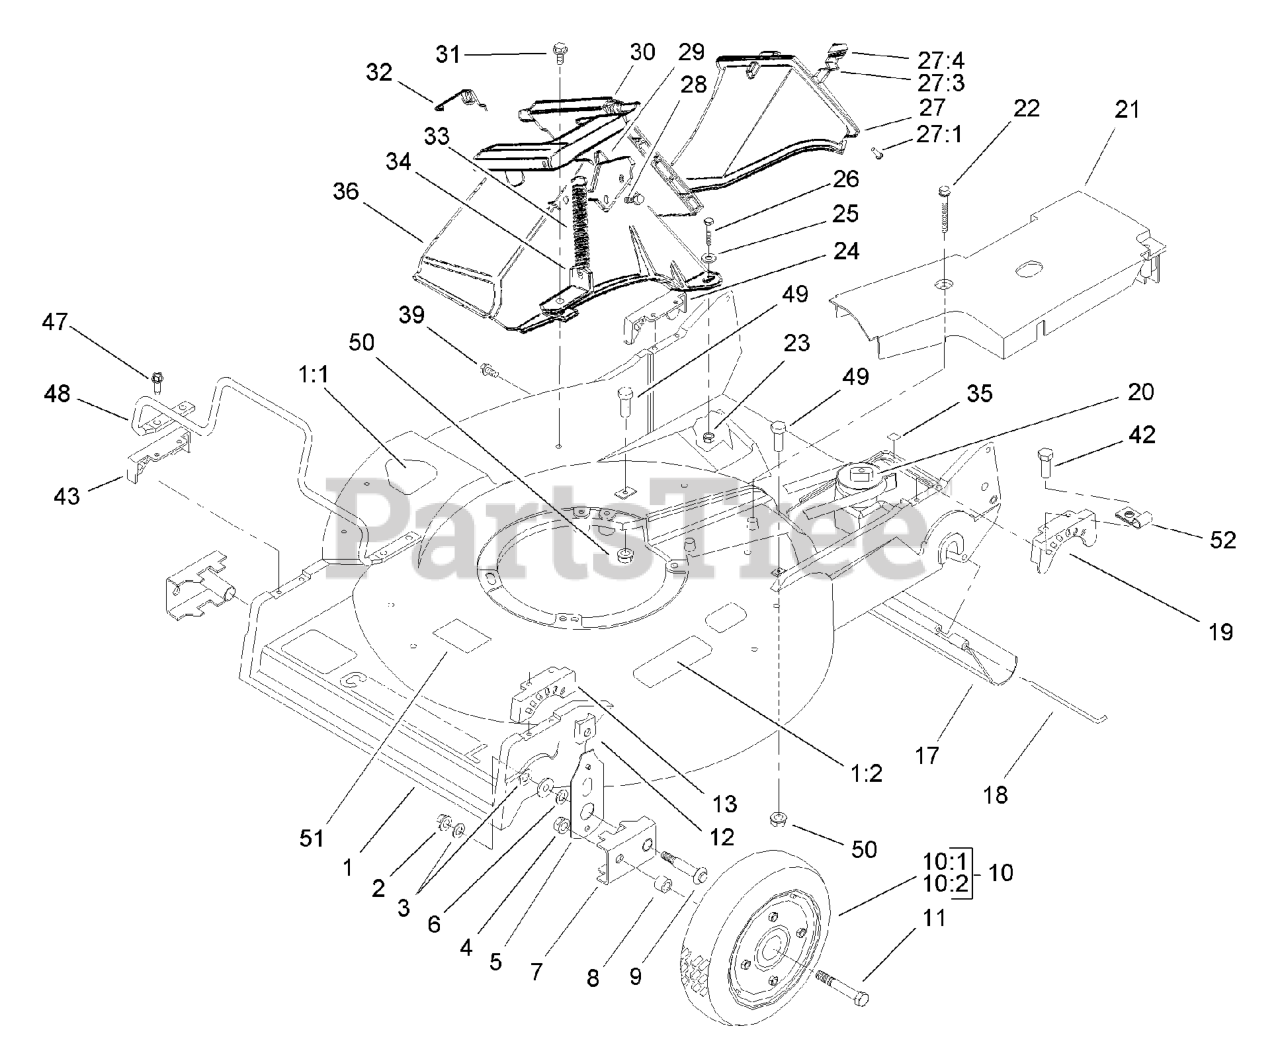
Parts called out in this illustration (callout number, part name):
1:1	DECAL-DANGER
1:2	DECAL-WARNING
2	NUT-LOCK
4	NUT-LOCK, CONE
5	FRONT SPRING ARM ASM
6	WASHER-THRUST
7	ARM-PIVOT, FRONT
8	SPACER-WHEEL
10:2	Wheel Asm
11	BOLT-CARR
12	KNOB-ARM
13	QUADRANT-FRONT, LH
18	ROD-SHIELD
19	QUADRANT-REAR, LH
21	COVER-BELT
22	SCREW-HWH
23	NUT-LOCK, NI
24	QUADRANT-REAR, RH
25	WASHER-FLAT
26	SCREW-HH
27	DISCHARGE PLUG ASM
27:1	RIVET-HEAD, FLAT
27:3	LATCH-PLUG, DISCHARGE
27:4	GRIP-LATCH
28	SCREW-PLASTITE
29	LATCH-PLATE
30	DISCHARGE DOOR ASM
31	SCREW-HWH
32	RETAINER-DOOR
33	SPRING-DOOR
34	BRACKET-SPRING
35	Label-Grease
36	TUNNEL-DISCHARGE
39	SCREW AND WASHER ASM
42	SCREW-HWHTF
43	QUADRANT-FRONT, RH
47	SCREW-HWHTF
48	GUARD-ENGINE
49	SCREW-HH
50	NUT-LOCK, NI
51	DECAL-BLADE
52	CLIP-CLOSED, INSULATED
